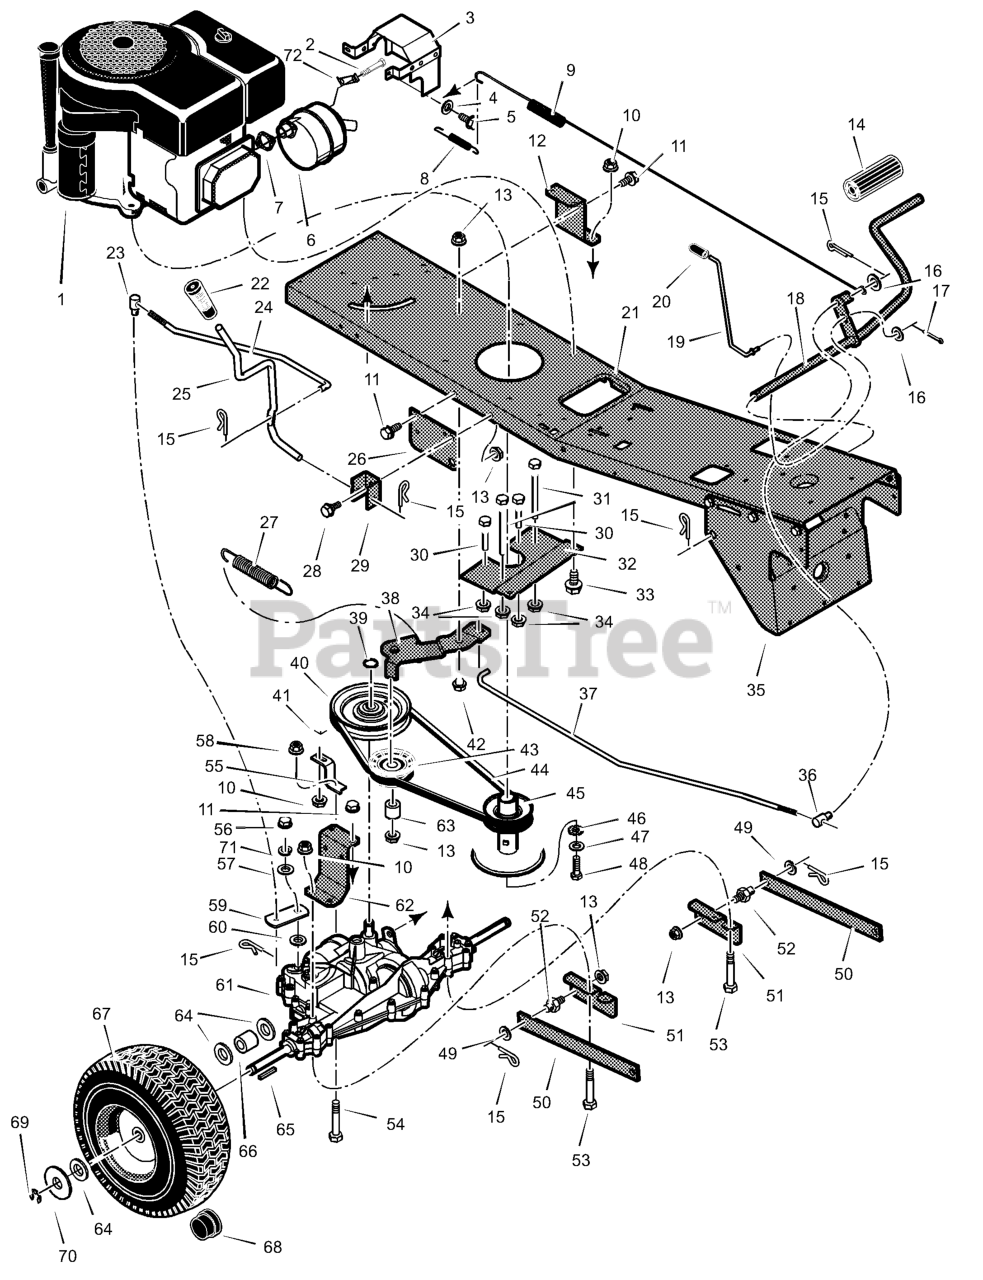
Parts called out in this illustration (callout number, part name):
1	Engine, Briggs & Stratton
2	Bolt, Hex
3	Shield Assembly, Heat
4	Lockwasher
5	Screw
6	Muffler
7	GASKET, Exhaust
8	Spring, Extension
9	Spring, Extension
10	Nut
12	Bracket, Transaxle -Left
13	Nut, Flange
14	Cover, Pedal
15	Pin, Cotter
16	Washer
17	Pin, Cotter
18	Pedal Assembly
19	Rod, Parking Brake
20	Grip, Parking Brake Rod
22	Grip, Shift Lever
23	Nut, Adjusting
24	Link, Shift
25	Lever, Shift
26	Bracket, Lift Pivot
27	Spring, Extension
28	Bolt, Shoulder
29	Bracket, Pivot
30	Guide, Belt -Short
31	Guide, Belt -Long
32	Plate, Belt Guide
33	Bolt
34	Nut, Flange
35	Bracket, Support
36	Nut, Adjusting
37	Rod, Clutch
38	Clutch Arm Assembly
39	Ring, Retainer
40	Pulley, Drive
41	Bolt, Carriage
42	Bolt, Shoulder
43	Pulley, Idler
44	Belt, Motion Drive
45	Pulley, Split Stack
46	Washer, Star
48	Bolt, Hex
49	Washer
51	Bracket, Rear Hanger
52	Pin, Threaded Shoulder
53	Bolt, Hex
55	Bracket, Torque Reactor
57	Washer, Shift Yoke
58	Nut
59	Yoke, Shift
61	Transaxle, Peerless **
62	Bracket, Transaxle
65	Key, Square
66	SPACER, Rear Wheel
67	Wheel, Rear -15" *
68	Cap, Hub
71	Lockwasher, Split
72	Lock, Screw
